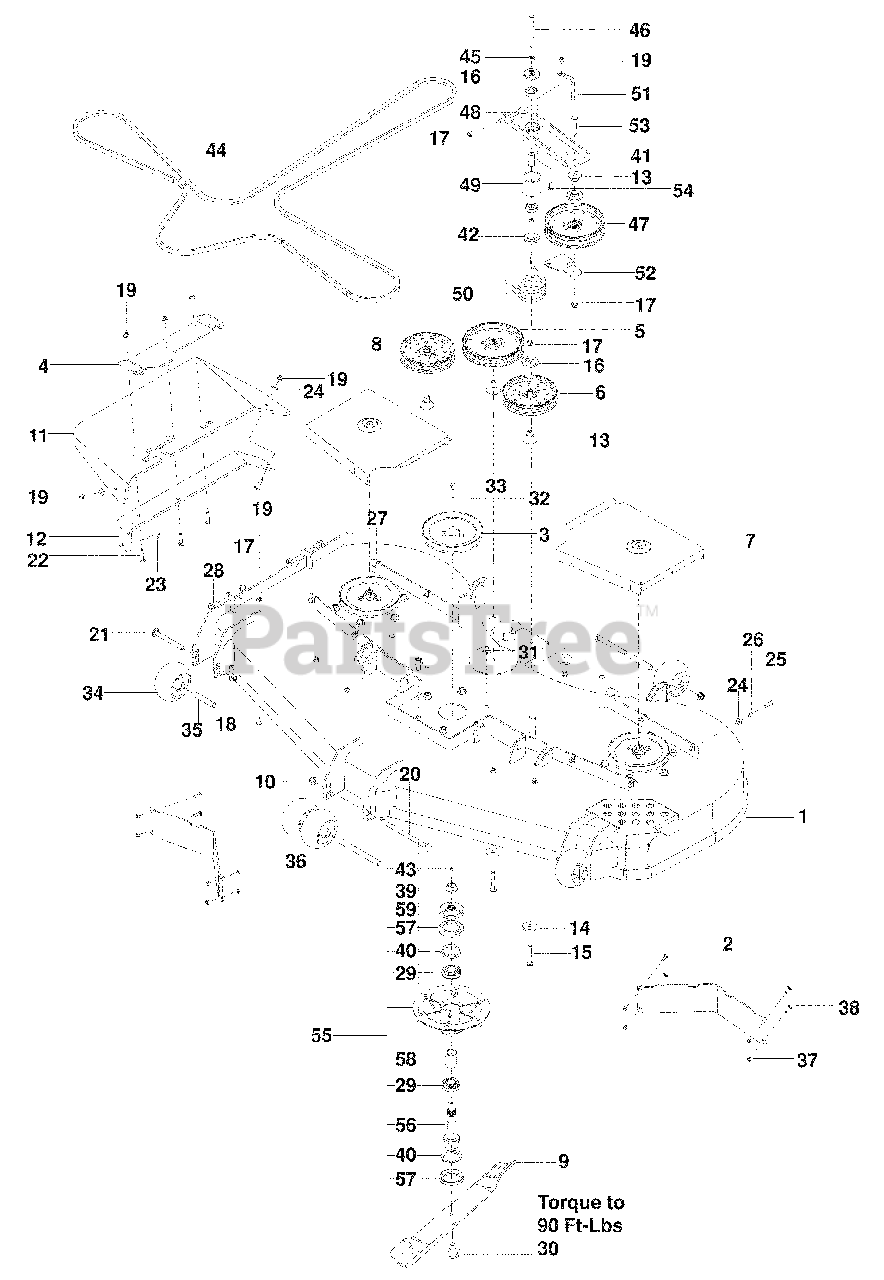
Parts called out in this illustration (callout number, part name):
1	DECK w/ SAFETY DECALS
2	BAFFLE, DIVERTER
4	BRACKET, CHUTE PIVOT
5	PULLEY, IDLER 7" NARROW
6	PULLEY, IDLER 6"
7	SHIELD, 72 RT
8	SHIELD, 72 LT
9	BLADE, 25"
10	NUT ½-13 HEX FLG NYLOC
11	CHUTE, DISCHARGE
12	BRACKET, CHUTE SUPPORT
13	BEARING, IDLER ARM
14	WASHER, HEAVY
15	SCREW 3/8-16 x 2¾ HEX FLG
16	SHIELD, DUST
17	NUT 3/8-16 HEX FLG NYLOC
18	SCREW 5/16-18 x ¾ HEX FLG
19	NUT 5/16-18 HEX FLG NYLOC
20	BOLT ½-13 x 8 RD HD
21	BOLT ½-13 x 4¾ RD HD
22	BOLT 5/16-18 x 1½ RD HD
23	BOLT 5/16-18 x 1¼ RD HD
24	WASHER 5/16 STD FLT
25	BOLT 5/16-18 x 1 HEX HD
26	WASHER 5/16 SLW
27	RETAINER, U TYPE
28	SCREW 3/8-16 x 1 HEX FLG
30	BLADE BOLT
31	SCREW ½-13 x 1 HEX FLG
32	WASHER 5/16 DISC SPRING
33	BOLT 5/16-18 x ½ HEX NYLOC
34	ROLLER, GAUGE
35	TUBE, ROLLER AXLE
36	TUBE, ROLLER AXLE LONG
37	NUT ¼-20 HEX NYLOC
38	BOLT ¼-20 x 1 RD HD
39	NUT ¾-16 FLG
41	ARM, IDLER w/ BRGS, SPACR
42	BEARING, IDLER PIVOT
43	ZERK
44	BELT, DECK
45	WASHER 3/8 THICK
46	BOLT 3/8-16 x 4½ HEX GR 8
47	PULLEY, IDLER 7" WIDE
48	EYEBOLT 3/8 x 4
49	SPACER, IDLER PIVOT
50	SPRING, TORSION
51	KEEPER, BELT
52	GUIDE, BELT
53	BOLT 3/8-16 x 2½ CARRIAGE
54	BOLT 5/16-18 x 1 RD HD
55	SPINDLE ASSY
56	SHAFT, SPINDLE
57	CUP, DEBRIS
